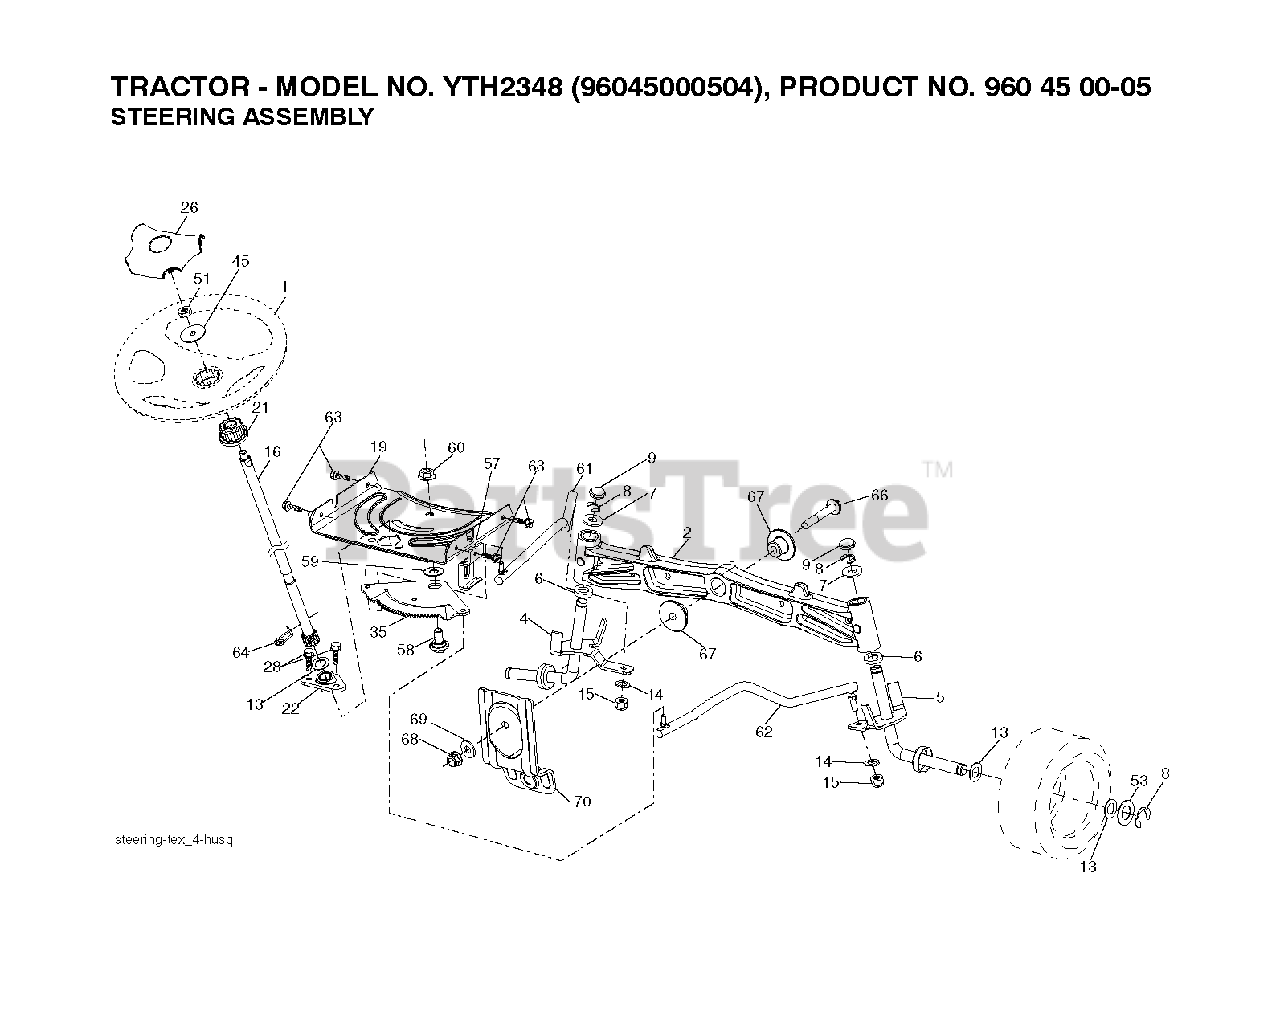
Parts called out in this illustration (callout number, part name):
1	WHEEL STEERING
2	AXLE.CAST.IRON
4	SPINDLE.WELDED.LH.15"TEX
5	SPINDLE.WELDED.RH.15"T
6	THRUST WASHER
9	CAP.SPINDLE.BLACK
14	WASHER, LOCK 3/8
15	NUT CROWNLOCK 3/8-24
16	SHAFT, STEERING
19	PLATE.STEER.DDL.NLT/NG
21	ADAPTER, WHEEL STNG..
22	BUSHING.ASM.STEERING.A
26	RP INSERT.CAP.WHL.STRG.HUSQ.
28	SCREW, 3/8-16X3/4
35	GEAR.SECTOR.PLATE.DDL.
45	WASHER 9/16"ID, 2 3/8"OD
51	NUT.HEX.1/2-20
53	WASHER.HARDENED
57	BRKT.UPSTOP.GT/LT.TEX
58	BOLT.SHOULDER.SECTOR.P
59	WASHER.THURST.SECTOR.S
60	NUT FLANGE LOCK 5/8-11
61	DRAGLINK.LH.BALLSTUD.D
62	DRAGLINK.RH.BALLSTUD.D
63	SCREW
64	RETAINER.CLIP.SPRING.S
66	BOLT HEX FGHD 7/16-14 X 3 SERR
67	BUSHING.PM.FRONT AXLE
68	NUT.LOCK.FLANGE.7/16
69	WASHER.1.5X.505X.118
70	BRKT.DECK.SUSPENSION.F
